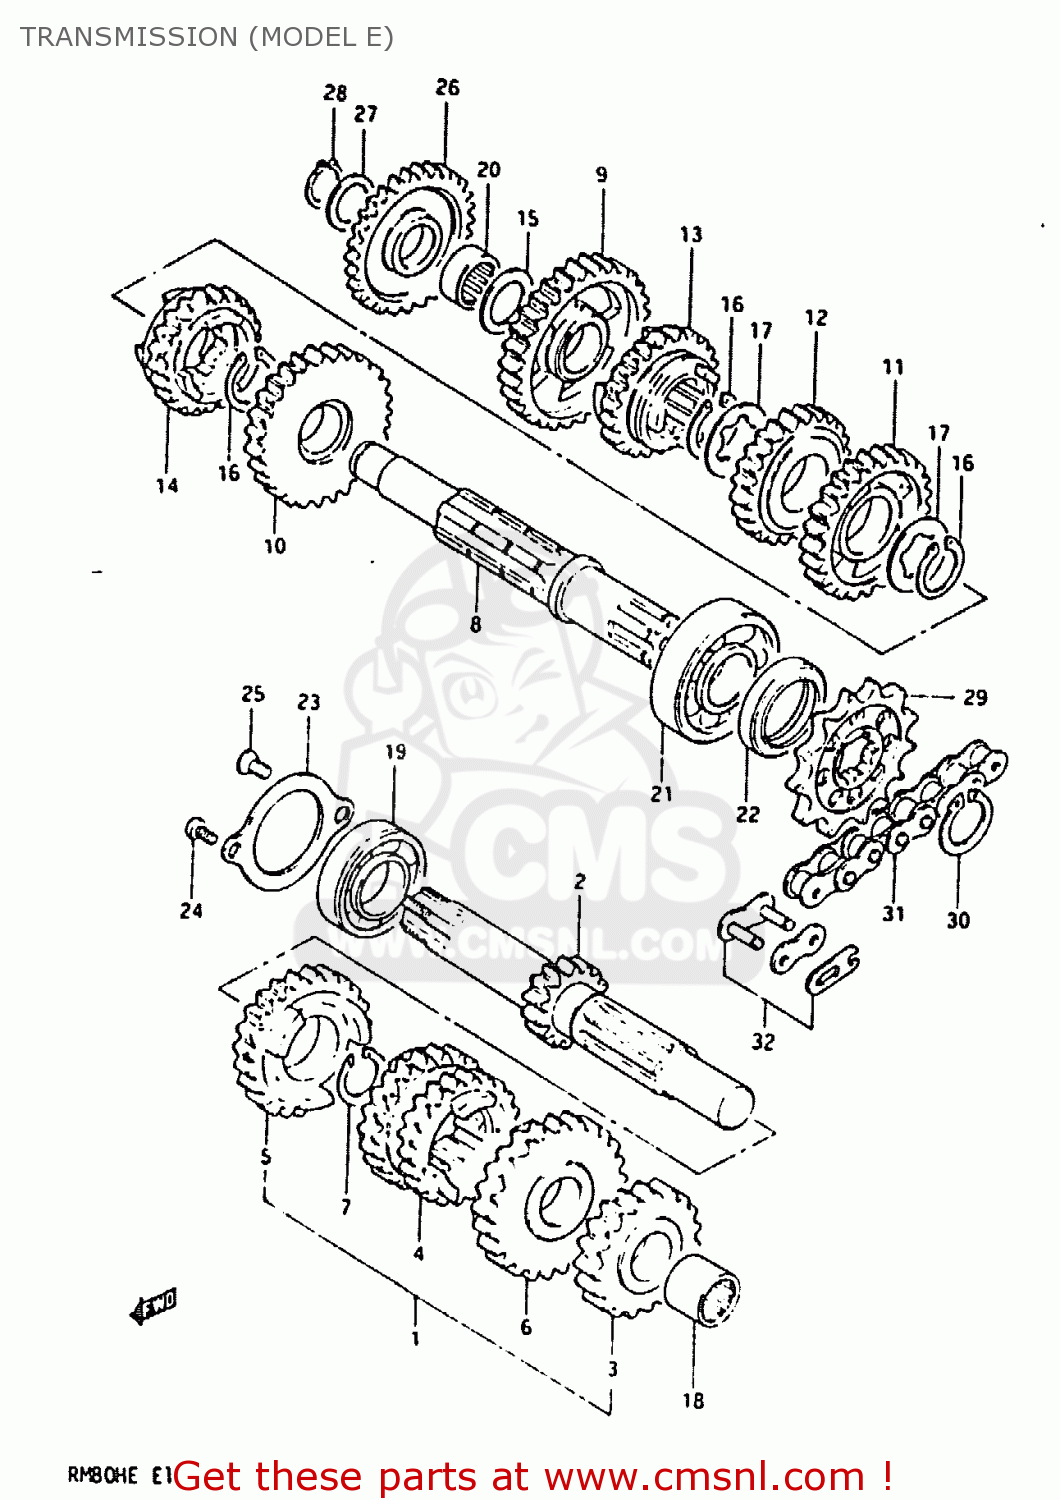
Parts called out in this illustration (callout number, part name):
1	SHAFT ASSEMBLY,COUNTER
2	SHAFT,COUNTER
3	GEAR,SECOND DRIVE
4	GEAR,THIRD & FOURTH DRIVE
5	GEAR,FIFTH DRIVE
6	GEAR,SIXTH DRIVE
7	CIRCLIP
8	SHAFT,DRIVE
9	GEAR,FIRST DRIVEN
10	GEAR,SECOND DRIVEN
11	GEAR,THIRD DRIVEN
12	GEAR,FOURTH DRIVEN
13	GEAR,FIFTH DRIVEN
14	GEAR,SIXTH DRIVEN
15	WASHER
16	CIRCLIP
17	WASHER,LOCK
18	ROLLER BEARING (13X19X1
19	BEARING
20	BEARING(15X21X12)
21	BEARING
22	OIL SEAL (20X35X5)
23	RETAINER,CNTR SHAFT BEARING
24	SCREW
25	SCREW
26	GEAR,KICK STARTER IDLER(NT:26)
27	THRUST WASHER
28	CIRCLIP
29	SPROCKET,ENGINE
30	CIRCLIP
31	CHAIN ASSEMBLY,DRIVE
32	JOINT,CHAIN
